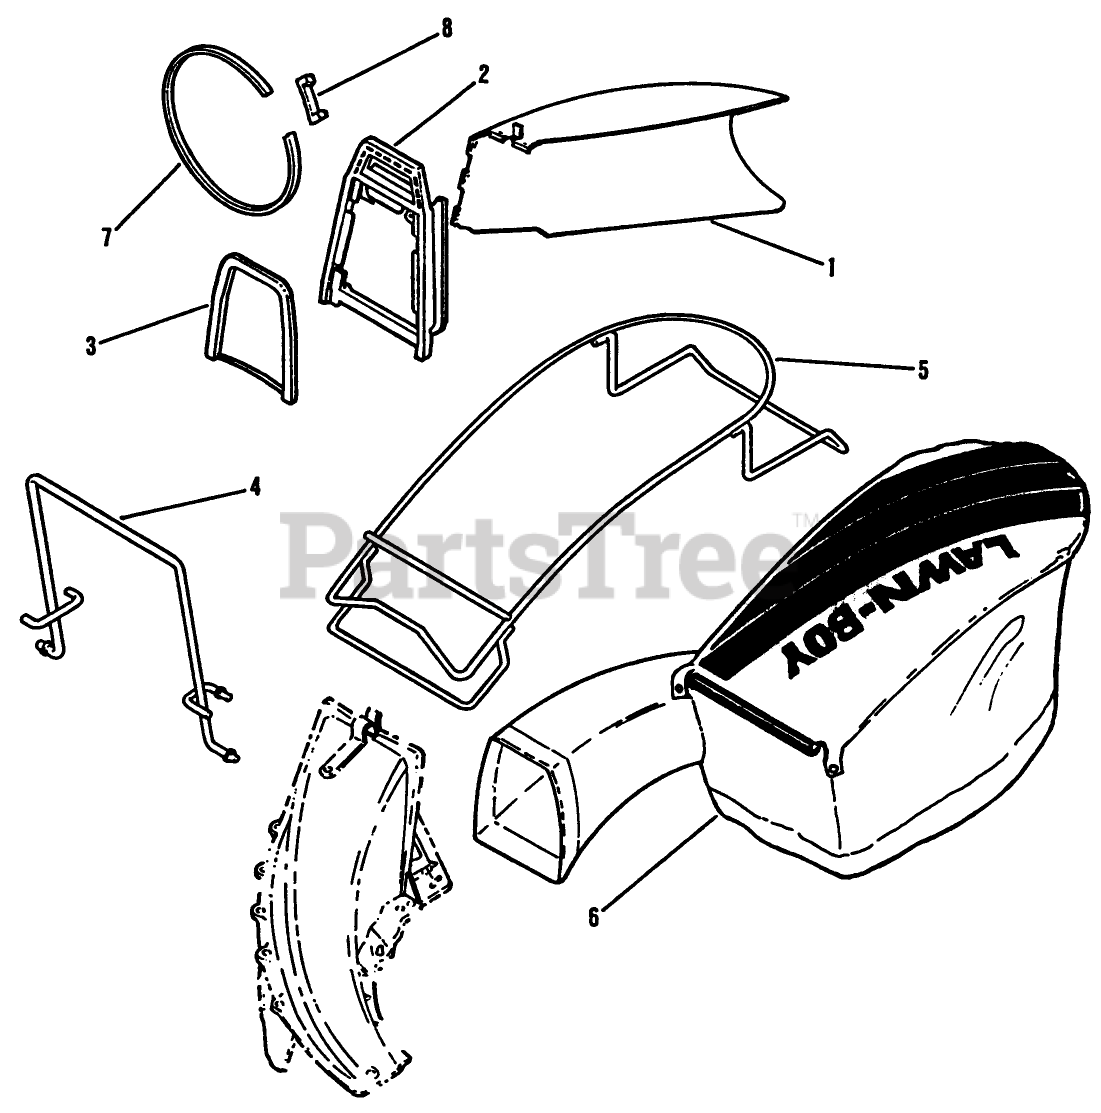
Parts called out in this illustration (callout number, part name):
1	DEFLECTOR REAR PL
2	CHUTE - ADAPTER
3	CHUTE BRACE
4	HANGER AY
5	DISCOUNTED
